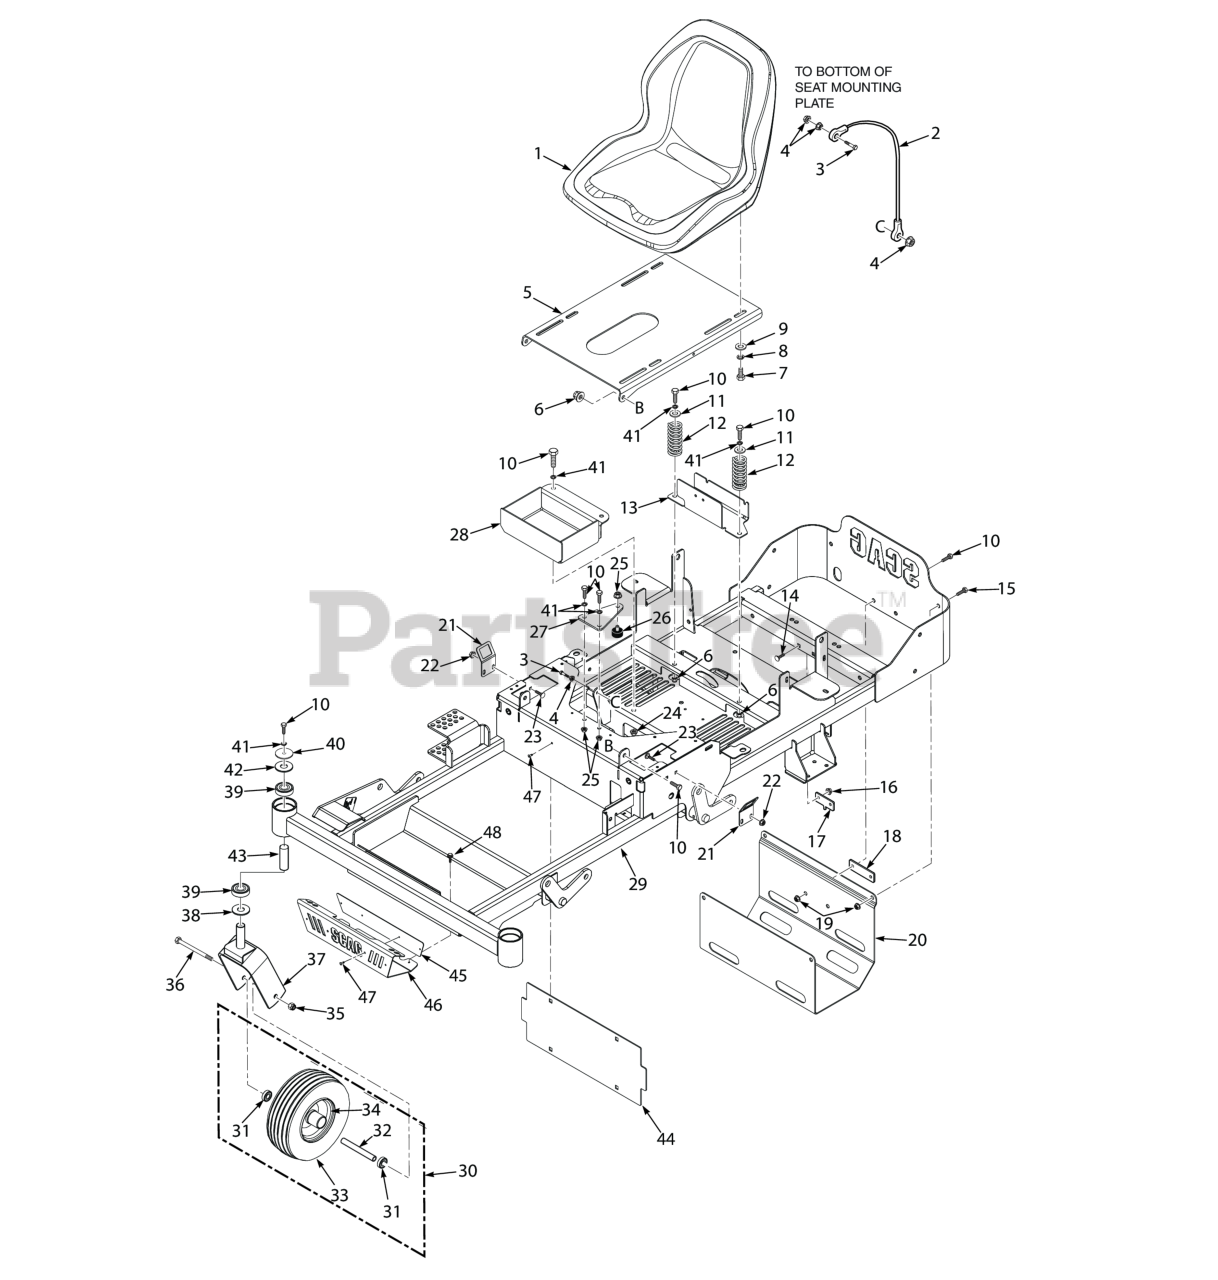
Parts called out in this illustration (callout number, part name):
1	Seat, SZL
2	Cable, Seat Stop
3	SERR. FLG. HEX HEAD CAPSCREW, 5/16-18 X 3/4
4	NUT, 1/4-20 SERRATED FLANGE HEX HEAD
5	Seat-Plate W/Decal
6	Nut, Flange Elastic Stop Nut, 3/8-16
7	Bolt, Heax Head 5/16-18 x 1" (48V / 52V)
8	Lockwasher, 5/16 (.317 x .586 x .078) Helical Spring
9	Flatwasher, 5/16-.375 x .875 x .083 (35BV & 37BV-EFI)
10	Bolt, Hex Head, 3/8-16 x 1 Gr. 5
11	Flatwasher, 3/8" Special (.391 x .938 x .105)
12	Spring, Seat
13	Seat Stop
14	Bolt, 5/16-18 x .75 RHSN Carriage
15	Bolt, Hex Head, 3/8-16 x 3/4"
16	Nut, Flange Head Elastic Stop 5/16-18
17	Plate, Anti-Rotation
18	Plate, Spacer
19	NUT, 3/8-16 SERRATED FLANGE HEX HEAD
20	Skid Plate, SZL-36
21	Bracket, Switch
22	Nut, Flanged Elastic Stop 1/4-20
23	Serr. Fl. Hex Head CPSCR, 1/4-20 x 3/4"
24	Threaded insert, Hex Head (Pressed)
25	Threaded insert, Hex Head (Pressed)
26	Bumper, Rubber 5/16-18 x 5/8"
27	Battery Hold Down
28	Battery Box
29	Frame Assembly, SZL-36
30	Caster Wheel Assembly
31	Bearing
32	Spacer, Wheel Bearings
33	Tire, 11 x 4-5.00 2-Ply
34	Rim Assembly
35	HEX LOCKNUT, ELASTIC STOP, 1/2-13
36	Bolt, Hex Head 1/2-13 x 6-1/2" (52V)
37	Caster Assembly
38	Spacer, Yoke
39	Bearing
40	Flatwasher, 3/8-.406 x 2.25" x .1875
41	Lockwasher, 3/8" Spring, Kawasaki FX / FS
42	Flatwasher, 7/16" (.500 x 1.25 x .083")
43	Spacer, Caster Bearing
44	Plate, Backing
45	Plate, Decal
46	Bumper. Front
47	Rivot, 3/16 x .402 POP
48	Screw, 1/4-20 x .375"
